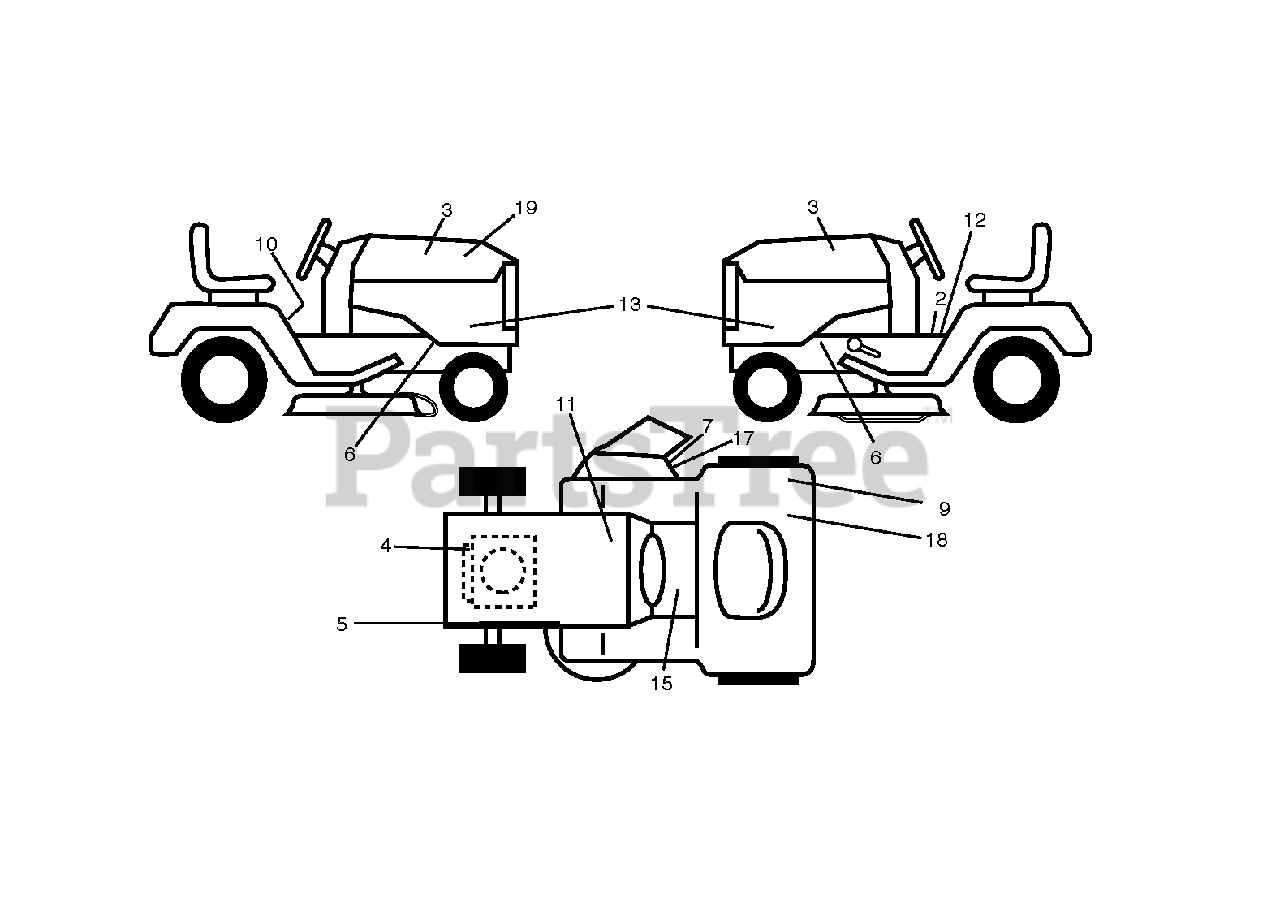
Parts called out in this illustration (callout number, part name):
2	DECAL PARK BRAKE
3	RP.DECAL.BADGE.170MM.TEXTLOGO
4	DECAL
5	DECAL V BELT SCHEMATIC
7	DECAL.INTERNATIONL.CUTFINGER
9	DECAL
10	LABEL
11	DECAL BTRY SYMBOLS
12	DECAL
15	DECAL
17	DECAL, DEFLECT WARNING
18	DECAL 80 DBA
